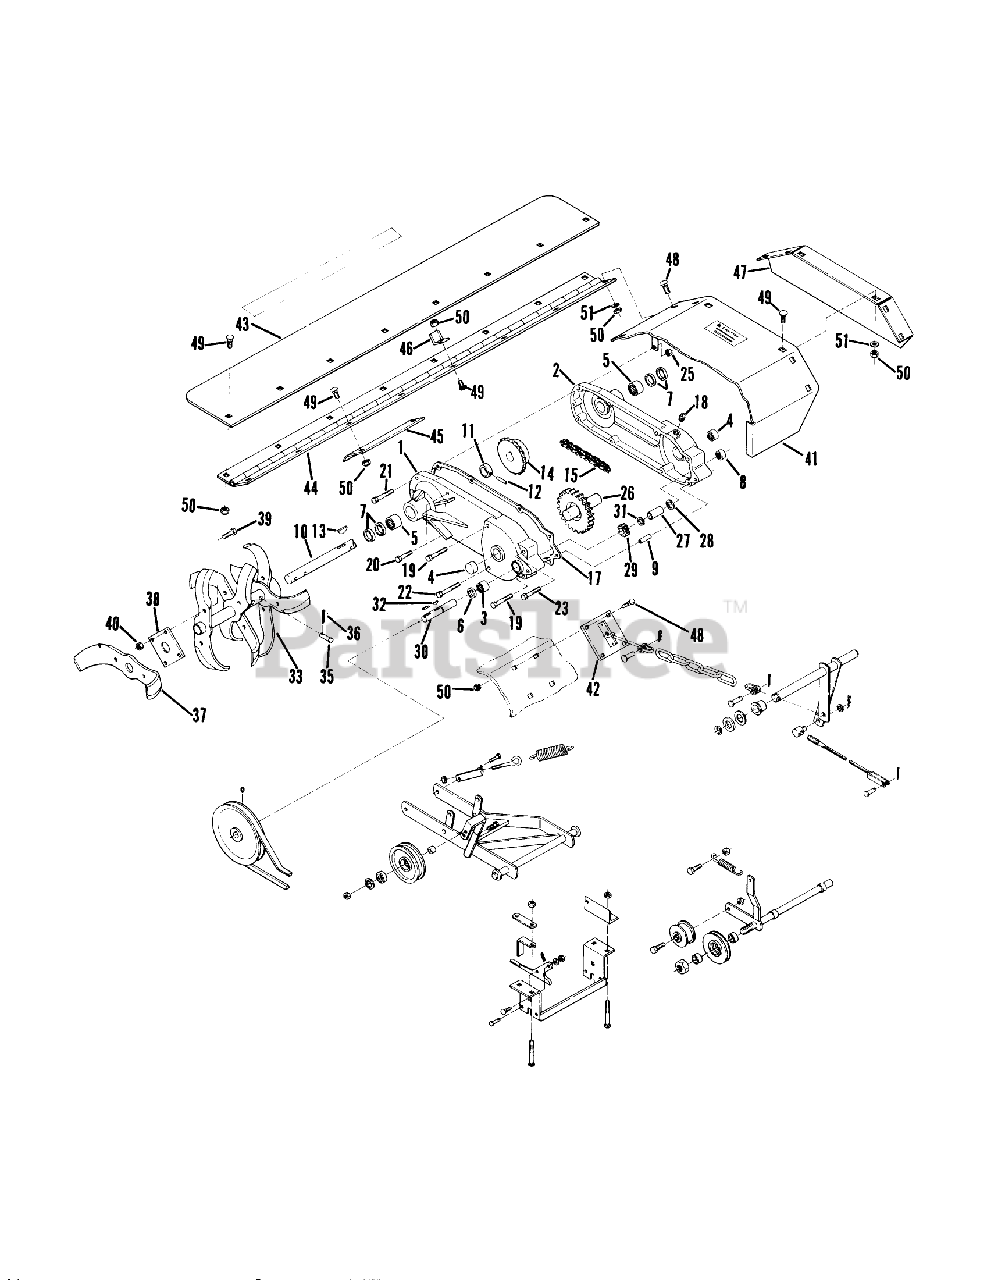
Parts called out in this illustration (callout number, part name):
1	R.H. Case (w/Bearings)
2	L.H. Case (w/Bearings)
3	BEARING-NEEDLE
4	BEARING-NEEDLE
5	BEARING-NEEDLE
6	SEAL-OIL
8	BEARING-NEEDLE
9	ROLL PIN 3/8 X 1
10	Shaft-Tine
11	Spacer
12	ROLL PIN 5/16 X 2
13	#128 Woodruff Key
14	Sprocket 20T
15	CHAIN
17	Gasket
18	SOLID PIPE PLUG
19	H H C S
20	Bolt
21	HHCS
22	BOLT
23	Hex Bolt
25	NUT
26	Gear-Reduction
26	Reduction Gear
26	Shaft
27	Spacer
28	WASHER-THRUST
29	GEAR-PINION
30	SHAFT-INPUT
31	RING-SNAP, EXTERNAL
32	Key
33	Tine R.H.
33	Tine L.H.
35	PIN-CLEVIS
37	R.H. Tine
37	L.H. Tine
38	Plate-Tine Mounting
39	H H C S
40	Nut
41	Tiller Tine Shield
42	Lift Plate
43	Rear Shield
44	Hinge
45	Lower Tine Guard Stop
46	Stop Bracket
47	Cover-End
48	Bolt
49	CARRIAGE BOLT -4
50	Nut
51	WASHER 5/16 SAE
